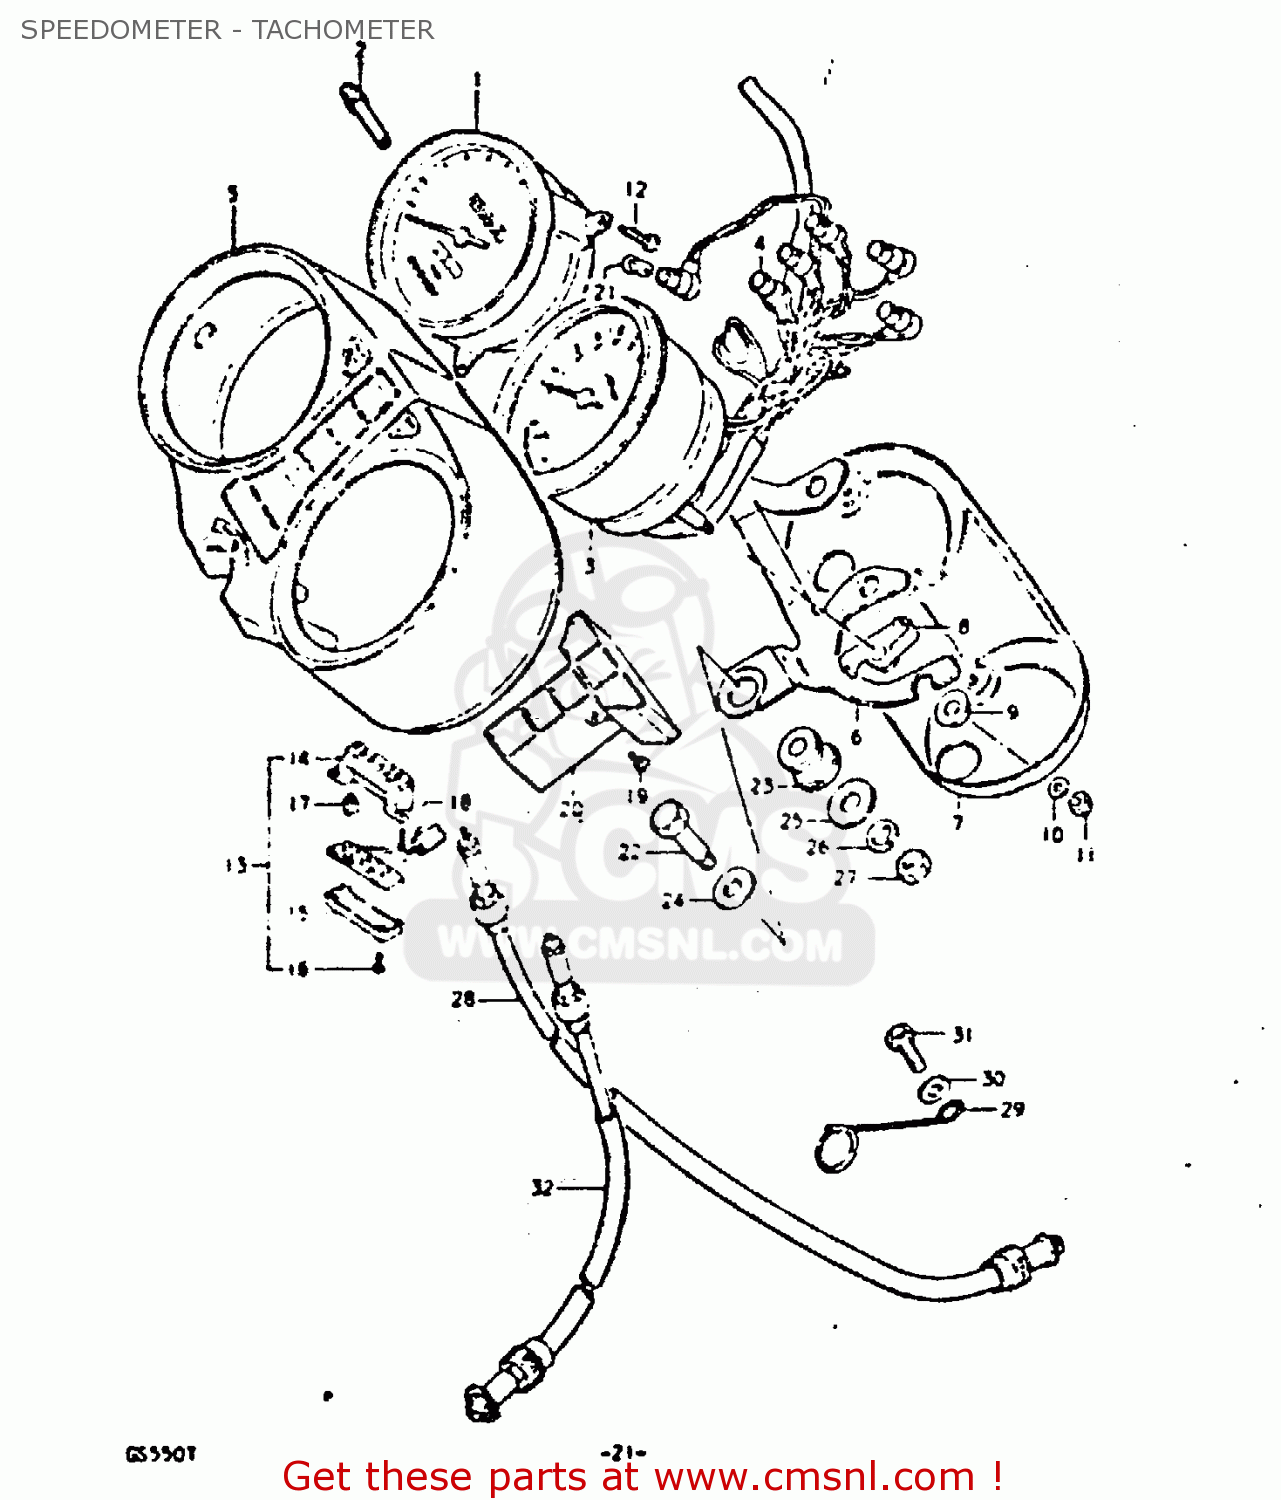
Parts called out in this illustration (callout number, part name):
1	METER,SPEEDOMETER (KM/MPH)
2	KNOB
3	TACHOMETER
4	SOCKET,METER
5	CASE
6	BRACKET,COMBINATION METER
7	COVER,UNDER
8	CUSHION,METER (B)
9	CUSHION,METER (A)
10	WASHER
11	NUT
12	SCREW
13	INDICATOR ASSEMBLY,GEAR POSITION
14	CASE,GEAR INDICATOR
15	COVER,LWR
16	SCREW,GEAR INDICATOR
17	BULB(14V1.12W)
18	SCREW
19	SCREW
20	BULB(12V3.4W,STANLEY,A72A)
21	CASE,PILOT BULB
22	BOLT(8X31)
23	CUSHION,METER
24	WASHER
25	WASHER (8.5X29X1.6)
26	LOCK WASHER
27	NUT
28	CABLE ASSEMBLY,SPEEDOMETER
29	GUIDE,SPEEDOMETER CABLE
30	WASHER
31	BOLT, UPPER
32	CABLE ASSEMBLY,TACHOMETER
